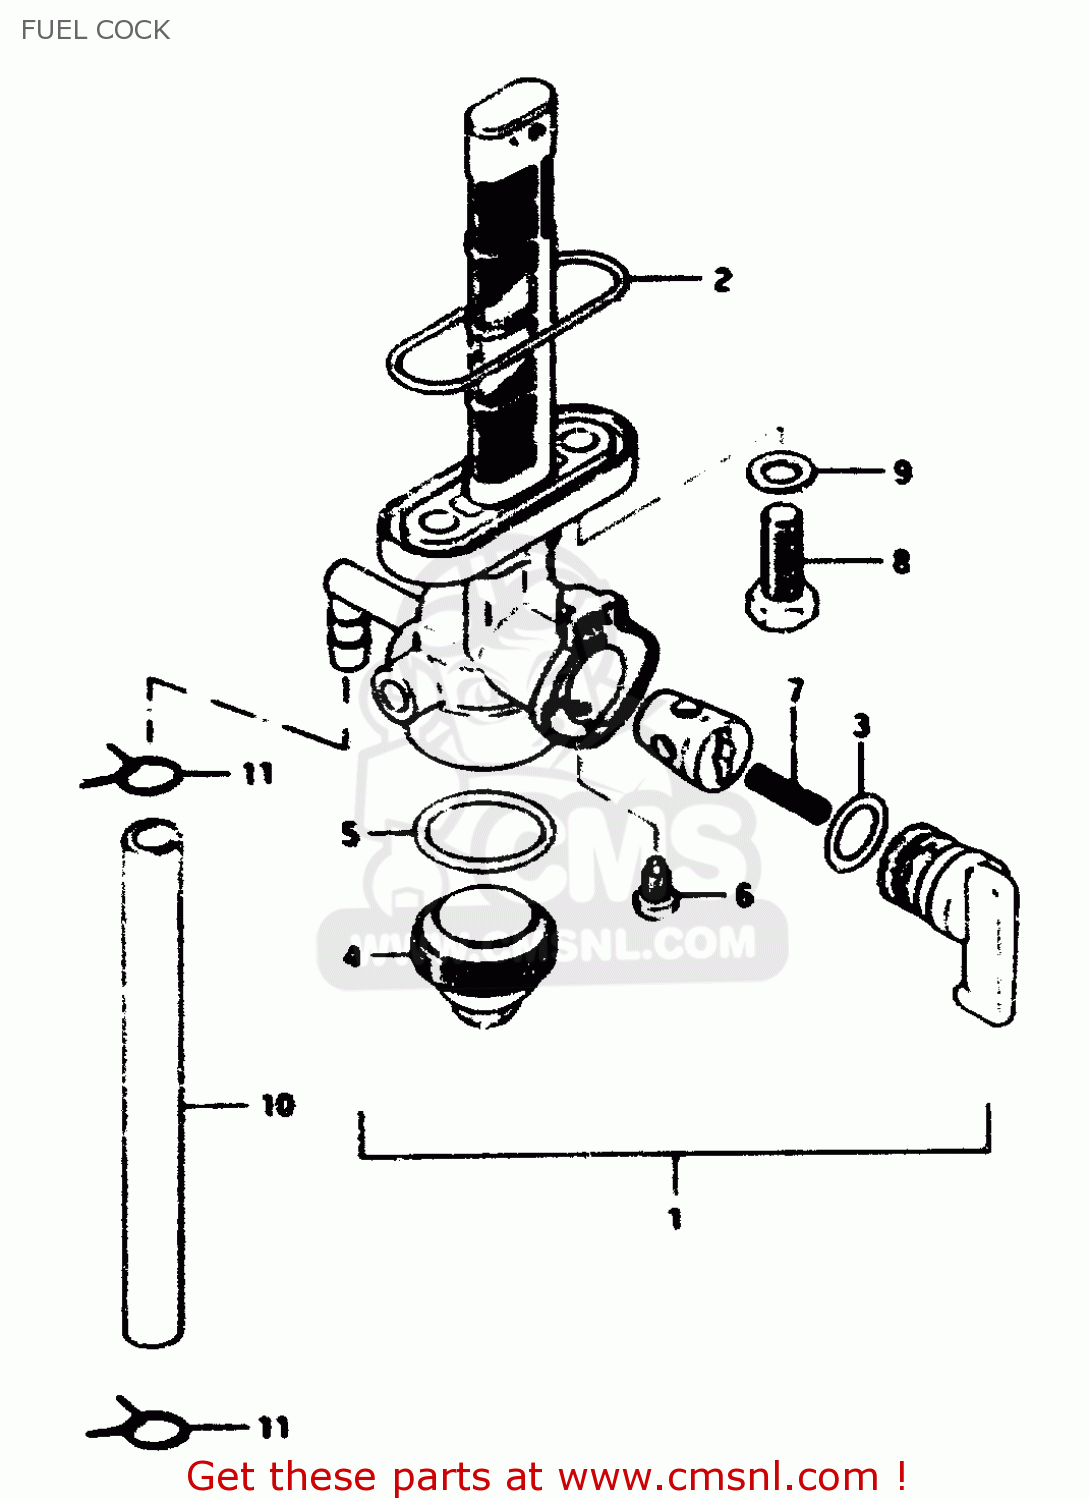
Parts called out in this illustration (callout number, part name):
1	COCK ASSY, FUEL
2	O RING,FUEL COCK
3	O-RING
4	CUP,STRAINER
5	GASKET,FILTER (NAS)
6	SCREW
7	SPRING
8	BOLT(6X20)
9	GASKET
10	HOSE
11	CLIP
